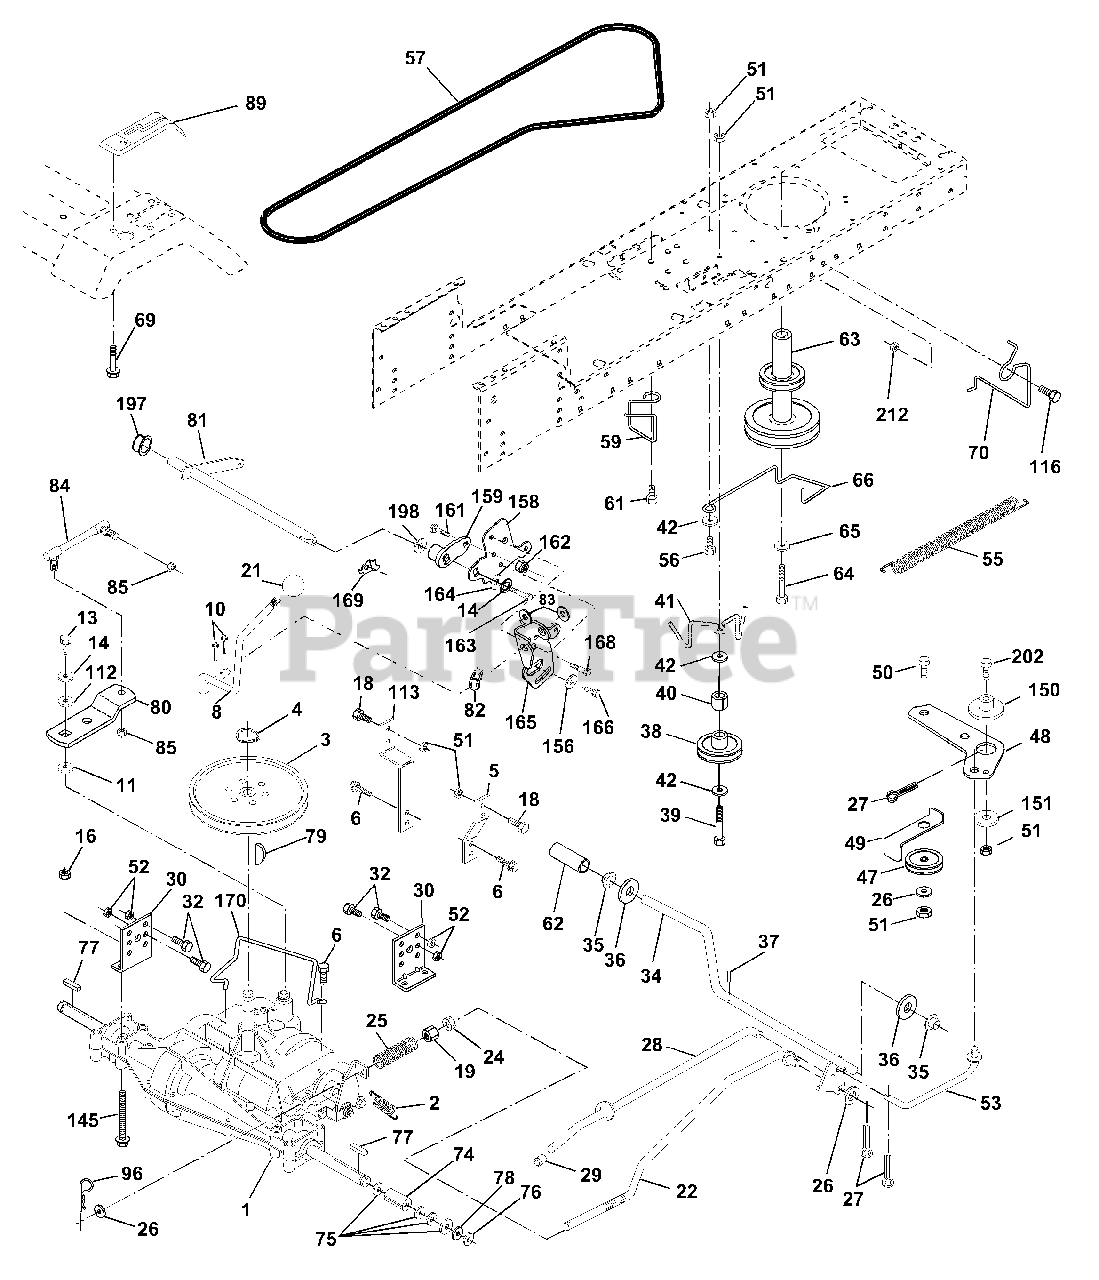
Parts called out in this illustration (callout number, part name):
2	Spring Return Brake T/a Zinc
3	Pulley Transaxle 18" tires
4	Ring Retainer #5100-62
5	Strap Torque 30 Degrees
6	Screw 5/16-18 X 3/4
8	Rod Shift Fender Adjust Lt
10	Pin Cotter 1/8 X 1 Cad
11	Washer Plate Shf 388 Sq Hole
13	Bolt 1/4-28 Unf Gr 8 W/Patch
14	Washer Lock Hvy Helical
16	Nut Lock Hex w/ins 5/16-18
18	Bolt, Fin Hex 3/8-16 UNC x 1 Gr. 5
19	Nut Lock 3/8-16 Unc
21	Knob
22	Rod Brake Blk Zinc 26 840
24	Nut Hex Jam 3/8-16 Unc
25	Spring Rod Brake 2 00 Zinc
26	Washer 13/32 X 13/16 X 16 Ga
27	Pin Cotter 1/8 X 3/4 Cad
28	Rod Brake Parking LT/YT
29	Cap Brake Parking
30	Bracket Mtg Transaxle
32	Bolt Hex Hd 5/16-18unc X 3/4
34	Shaft Asm Pedal Foot
35	Bearing Nylon Blk 629 Id
36	Washer 21/32 X 1 X 16 Ga
37	Pin Roll 3/16 X 1"
38	Pulley Idler Flat
39	Bolt Fin Hex 3/8-16 unc X 2-3/4
40	Spacer Split 395 X 59 Bzp
41	Keeper Belt Flat Idler
42	Washer 13/32 X 13/16 X 12 Ga
47	Pulley Idler V Groove Plastic
48	Bellcrank Asm
49	Retainer Belt Style Spring
50	Bolt Hex Hd 3/8-16unc X 1-1/2
51	Nut Crownlock 3/8-16 Unc
52	Nut Crownlock 5/16-18 Unc
53	Link Clutch
55	Spring Return Clutch 6 75
56	Bolt Fin Hx 3/8-16 X 1/4
57	V-Belt Ground Drive 95 25
59	Keeper Belt Span Ctr
61	Screw 3/8-16x.75
62	Cover Pedal Blk Round
63	Engine Pulley LT/YT
64	Bolt Hex
65	Washer Lock Hvy Hlcl Spr 7/16
66	Keeper Belt Engine Foolproof
69	Screw Hex wsh Hi Lo 1/4 x 1/2 unc
70	Guide Belt Mower Drive RH
72	Washer 13/32 X 1-1/4 X 12 Ga
74	Spacer Axle
75	Washer 25/32 X 1 1/4 X 16 Ga
76	E-ring #5133-75
77	Key Square 2 0 X 1845/ 1865
78	Washer 25/32 X 1-5/8 X 16 Ga
79	Key Woodruff #9 3/16 x 3/4
80	Arm Shift
81	Shaft Asm Cross Tapered PMST/20
82	Spring Torsion T/a
83	Washer 17/32 X 3/4 X 16 Ga
84	Link Transaxle PMST/20" Zinc
85	Nut Lock Center 1/4 - 28 FNTHD
89	Console Shift STLT
96	Retainer Spring 1"
112	Washer 9/32 x 3/4 x 10 Ga.
113	Strap Torque LT
116	Bolt RDHD SQNK 3/8-16 Unc x 1
145	Bolt Hex FLGHD 5/16-18 Gr. 5
150	Bushing Bellcrank
151	Washer 13/32 x 2 x 10
156	Washer Srrted 5/16ID x 1.125
158	Bracket Shift Mount
159	Hub Tapered Flange Shift Lt
161	Bolt Rdhd Sqnk 1/4-20 x 3/4 Gr
162	Nut Crownlock 1/4-20 Unc
163	Bolt Hex Fin 1/4-20 Unc x 1 Gr 5
164	Washer 5/8 x .281 x 10 Ga
165	Bracket Pivot Lever
166	Screw 5/16-18 x 5/8
168	Bolt Shoulder 5/16-18 x .561
169	Plate Fastening
170	Keeper Belt Transaxle Gear
197	Nyliner Snap-In
198	Washer Nyliner
202	Bolt Carr Sh 3/8-16 x 1-1/2 Gr. 5
212	Nut Hex Flange Lock
